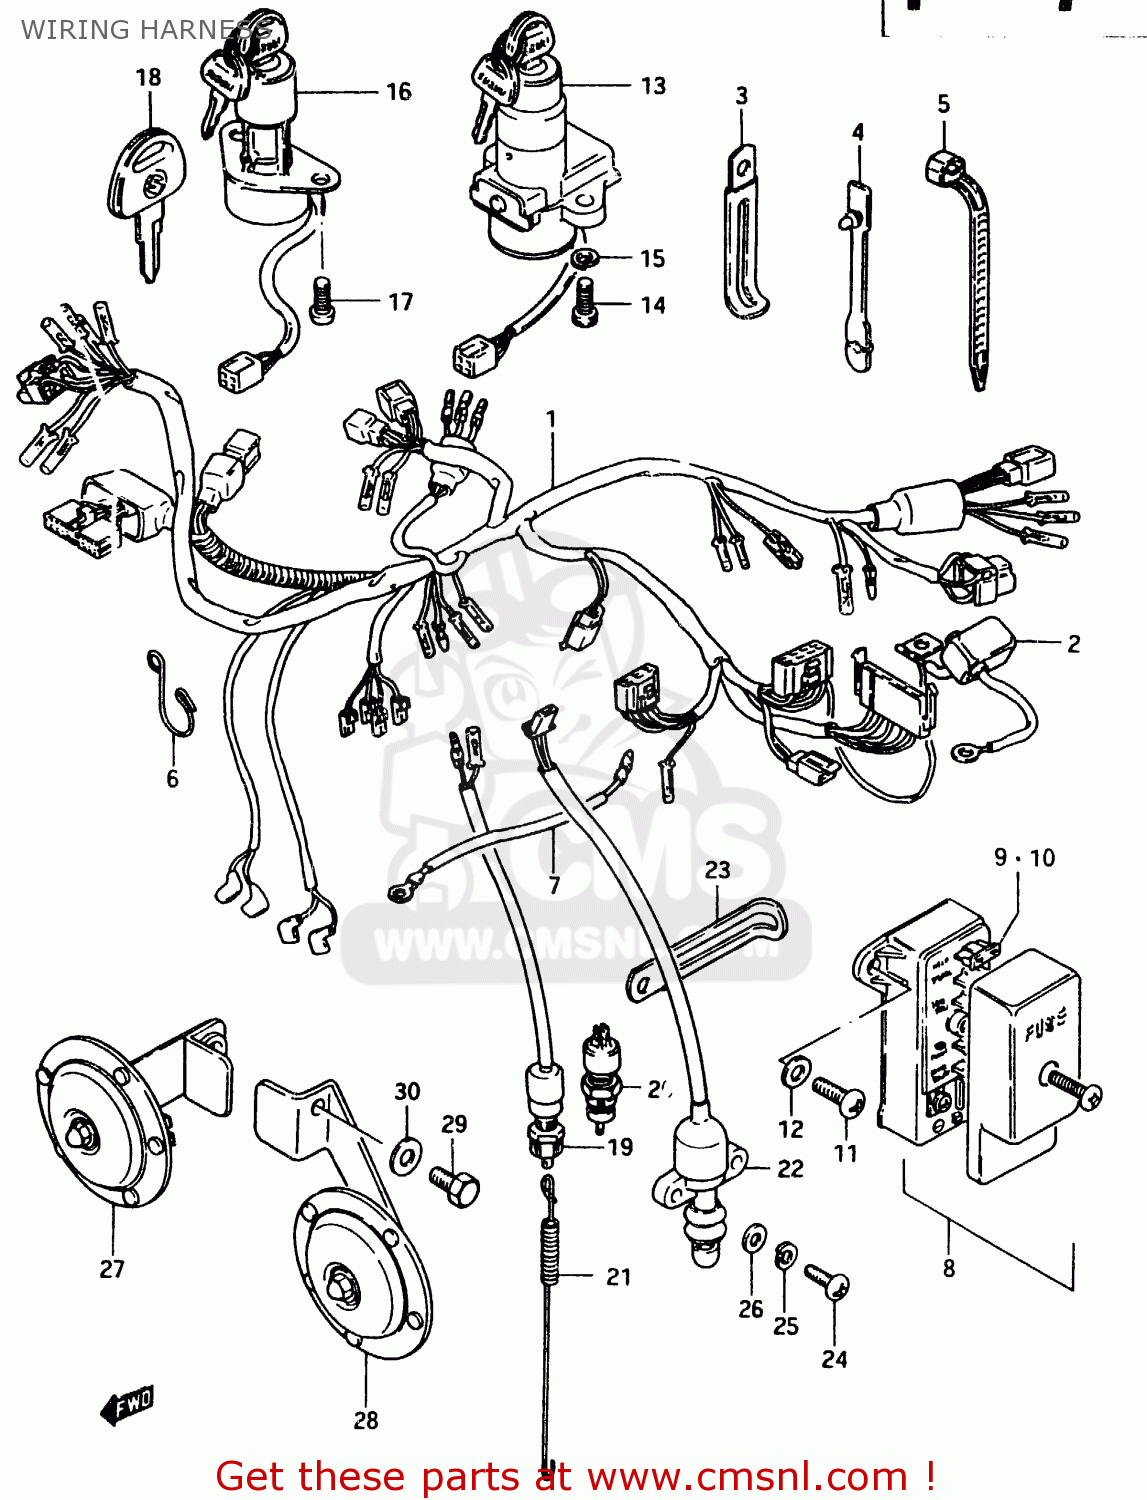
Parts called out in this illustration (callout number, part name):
1	HARNESS,WIRING
2	CAP,BATTERY PLUS TERMINAL
3	CLAMP
4	CLAMP,L:88
5	CLAMP(L:95)
6	CLIP,WIRING HARNESS
7	WIRE
8	BOX ASSEMBLY,FUSE
9	FUSE(10A)
10	FUSE(15A)
11	SCREW
12	WASHER, LOWER
13	LOCK ASSEMBLY,STEERING
14	BOLT
15	LOCK WASHER
16	SWITCH ASSY, IGNITION
17	SCREW 6X12
18	KEY,BLANK
19	SWITCH ASSY,STOP LAMP
20	SWITCH ASSEMBLY,STOP LAMP
21	SPRING
22	SWITCH ASSEMBLY,SIDE STAND
23	CLAMP
24	SCREW 5X20
25	WASHER,LOCK
26	WASHER,5MM
27	HORN ASSEMBLY
28	HORN ASSEMBLY
29	BOLT
30	WASHER,8.5X16X
